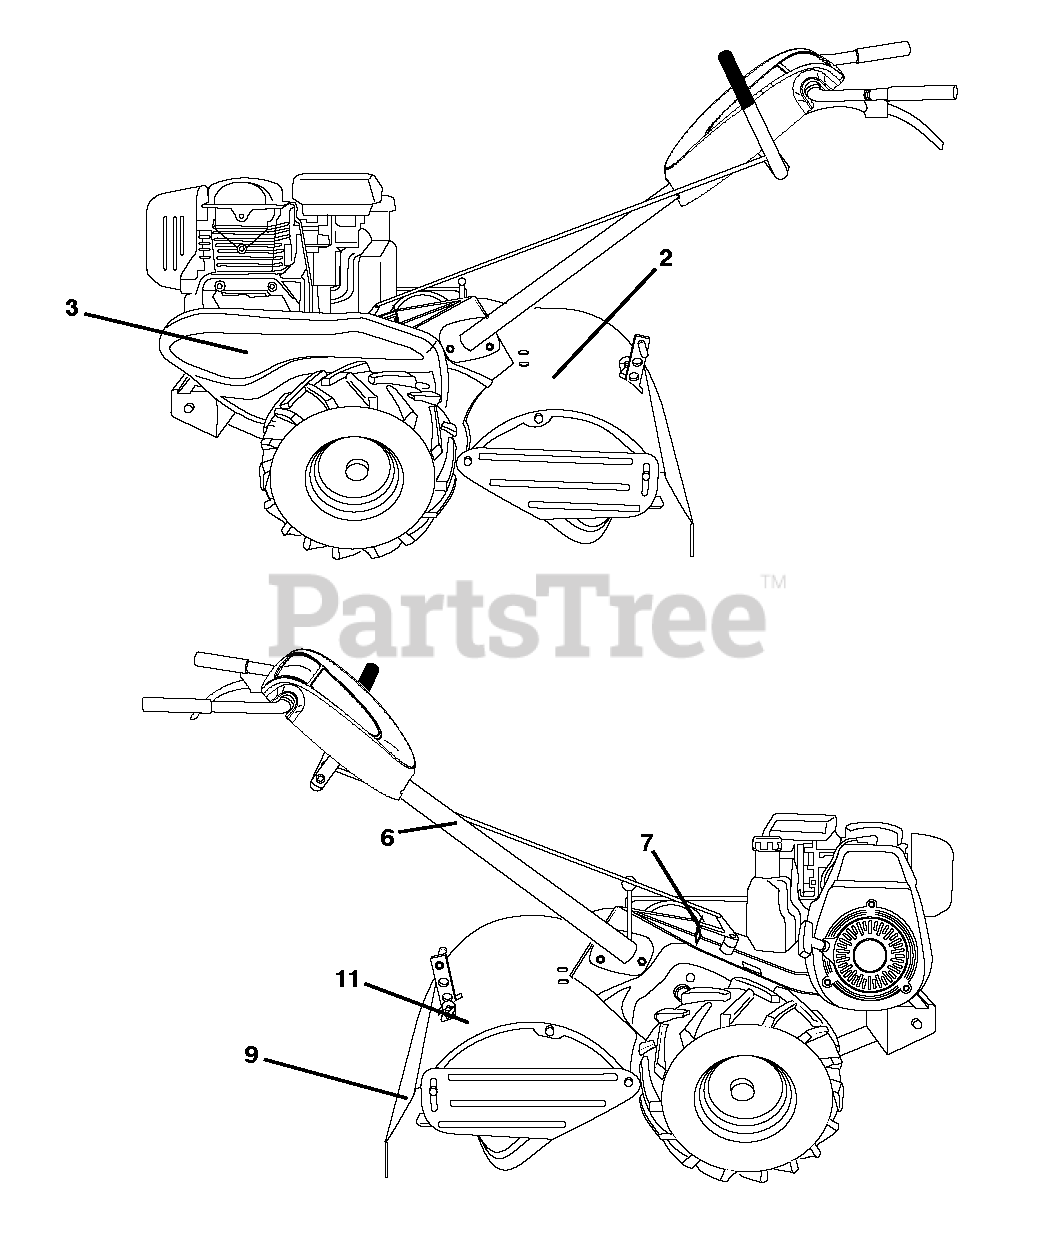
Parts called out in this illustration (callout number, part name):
2	Husqvarna TBD
3	RP.DECAL.BADGE.170MM.TEXTLOGO
6	DECAL TI (2 2)
7	DECAL.SHIFT.INDICATOR.TILLER
9	DECAL TI
11	DECAL.WARNING.SHLD.ENG/FR
